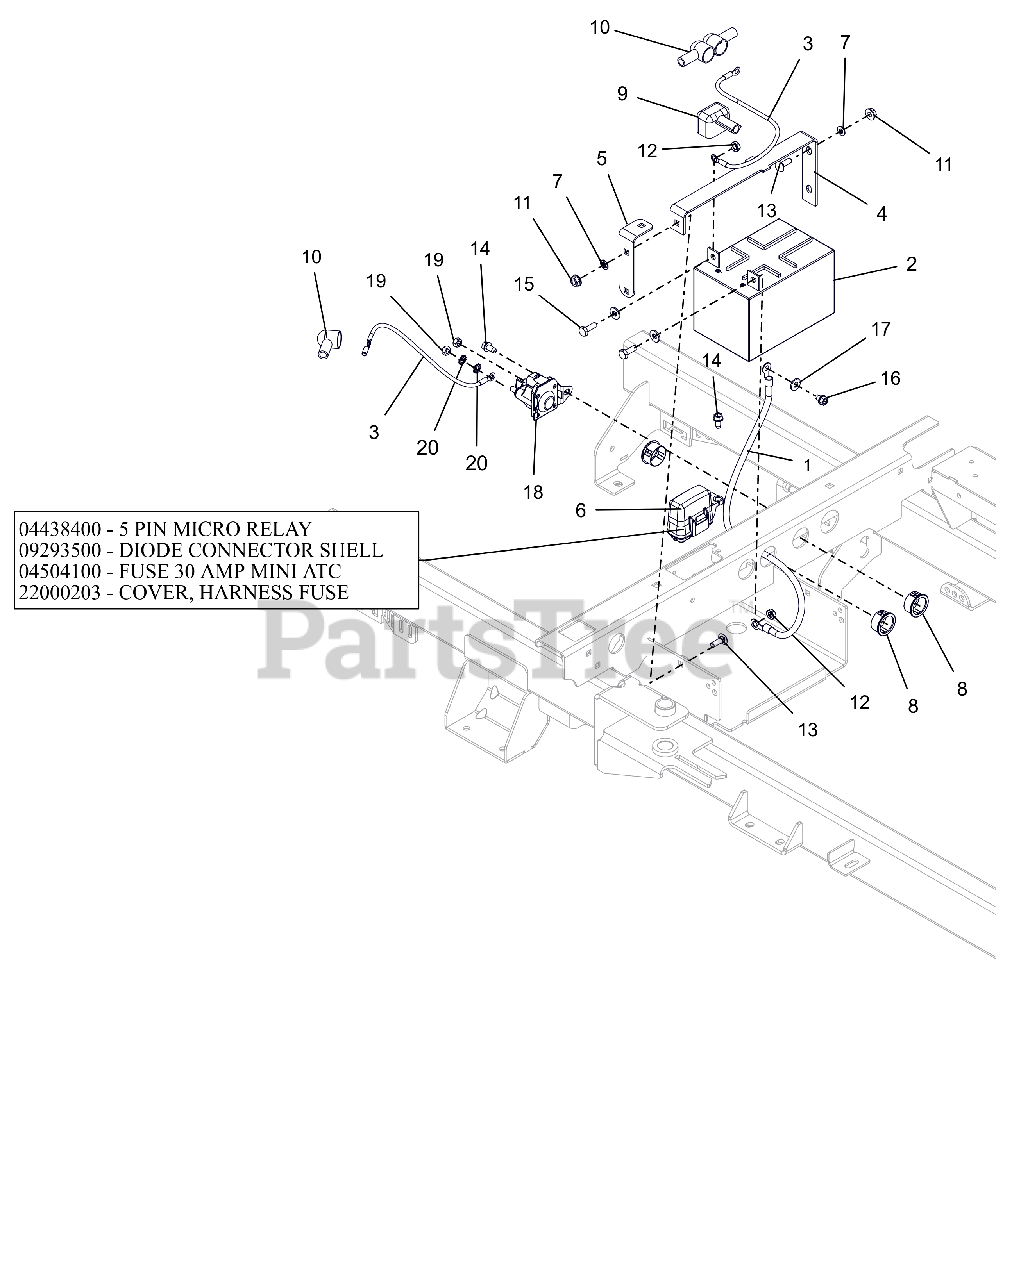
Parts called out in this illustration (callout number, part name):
1	CABLE-NEGATIVE BATTERY 24.00"
2	BATTERY, 12V 12A-190CCA
3	CABLE,POS W/2 1/4 RING 15.0 LG
4	BRKT, BATTERY HOLD-DOWN
5	BRKT, BATTERY HOLD DOWN
6	HARNESS, WIRE-4POS KEY IKON/ZT
6	RELAY,MICRO5 TERML W/RESISTOR
6	DIODE, CONNECTOR SHELL
6	FUSE,30 AMP MINI-ATC
6	COVER, FUSE
7	NUT-PUSH .25X.50 O.D.
8	BSHG, PANEL SNAP .937X1.11X.56
9	INSULATOR
10	BOOT, EYELET TERMINAL
11	NUT-LK-TOP-FLG .250-20 GF ZCC
12	NUT-KEPS .250-20
13	BLT, RHSN .25-20X.750 G5 ZCC
14	SCR-TAP .25-20X.50 HWH ZCC
15	BLT, HEX .25-20X.75 G5 ZCC
16	SCR,TAP .25-20X.375 HWH TR ZCC
17	WSHR,FLT .281X.625X.065 ZCC
18	SOLENOID, STARTER (SEALED)
19	NUT-STD M6-1.0 ZCC
20	WSHR,LK-EXT.262X.502X.026 ZCC
